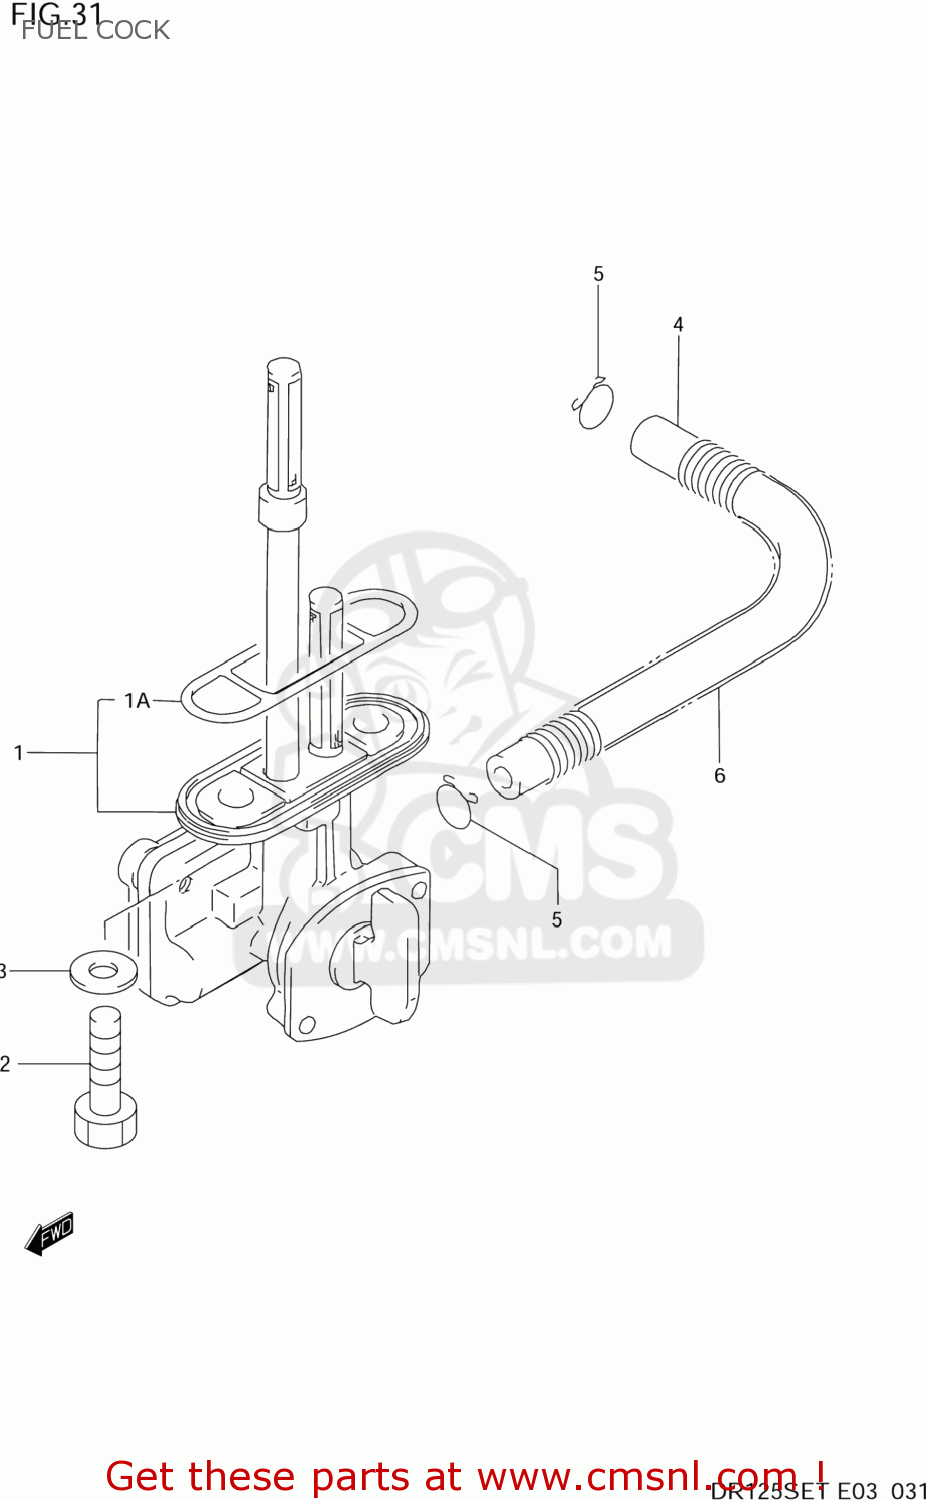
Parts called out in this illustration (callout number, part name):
1	COCK ASSY,FUEL
1A	GASKET,JOINT (NAS)
2	BOLT(6X20)
3	GASKET(6.4X11.5X0.8) (NAS)
4	HOSE(5X8.2X600)
5	CLIP
6	SPRING
